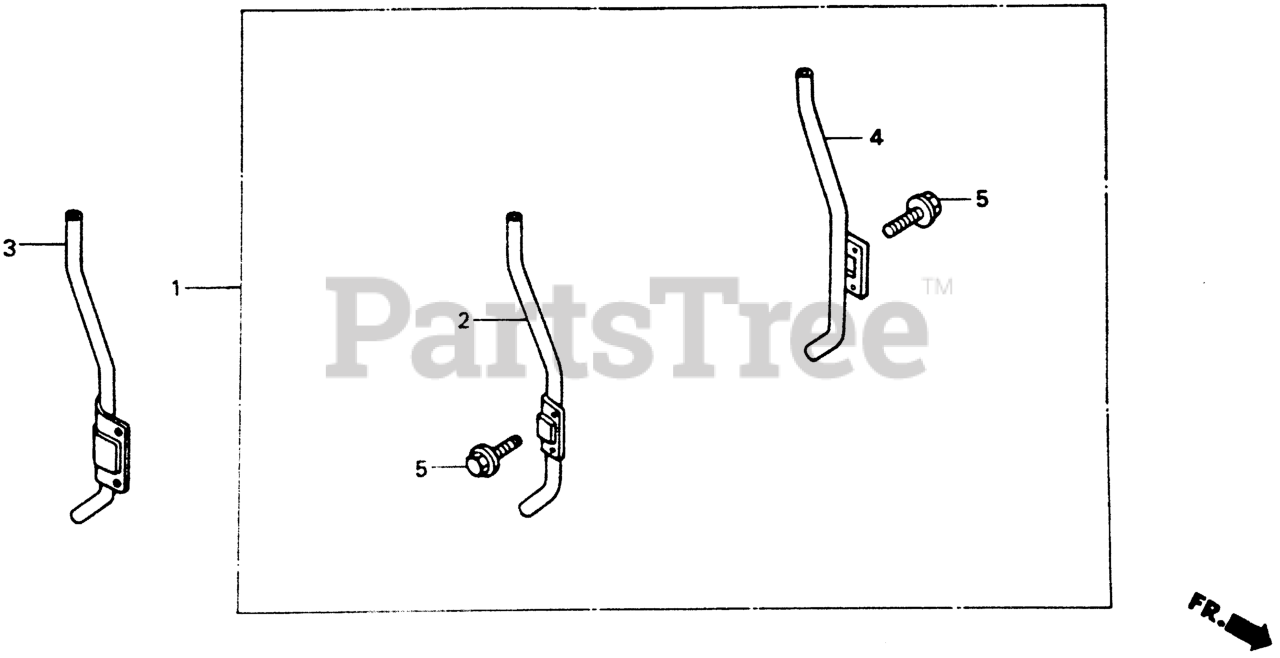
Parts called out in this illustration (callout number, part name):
1	STAND KIT, SUPPORT
2	POST, R. SUPPORT (NOT AVAILABLE)
4	POST, L. SUPPORT
5	BOLT, FLANGE (8X20)
